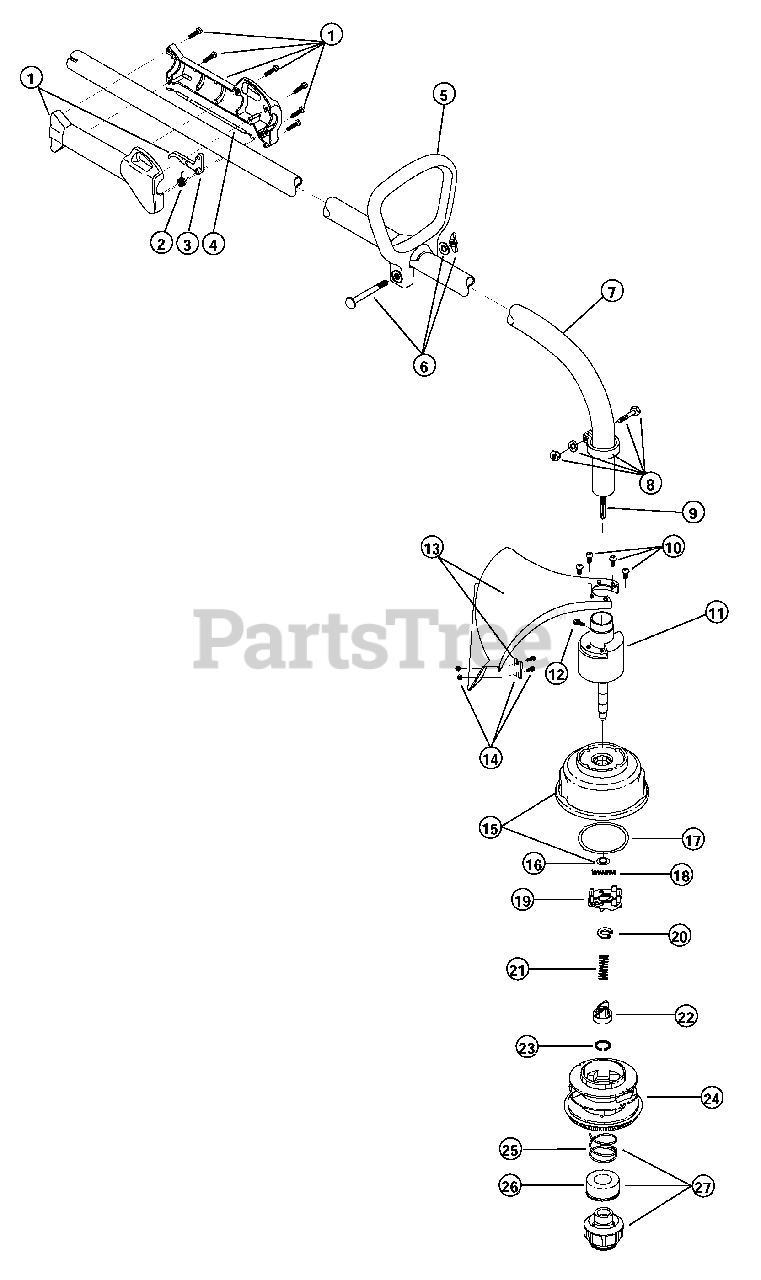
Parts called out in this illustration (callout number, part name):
1	Throttle Housing & Trigger Assembly
2	Throttle Trigger Spring
3	Throttle Trigger
4	Throttle Cable Assembly
5	D-Handle Assembly
6	D-Handle Hardware
7	Drive Shaft Housing Assembly
8	Lower Clamp Assembly
9	Flexible Drive Shaft
10	Shield Mounting Screw
11	Bushing Housing Assembly
12	Anti-Rotation Screw
13	Shield and Blade Assembly
14	Blade Assembly
15	Outer Spool Assembly w/ Retainer
16	Retainer
17	Thrust Washer
18	Small Spring
19	Slider
22	Plunger
24	Inner Reel
25	Large Spring
26	Foam Seal
27	Bump Head Knob Assembly
